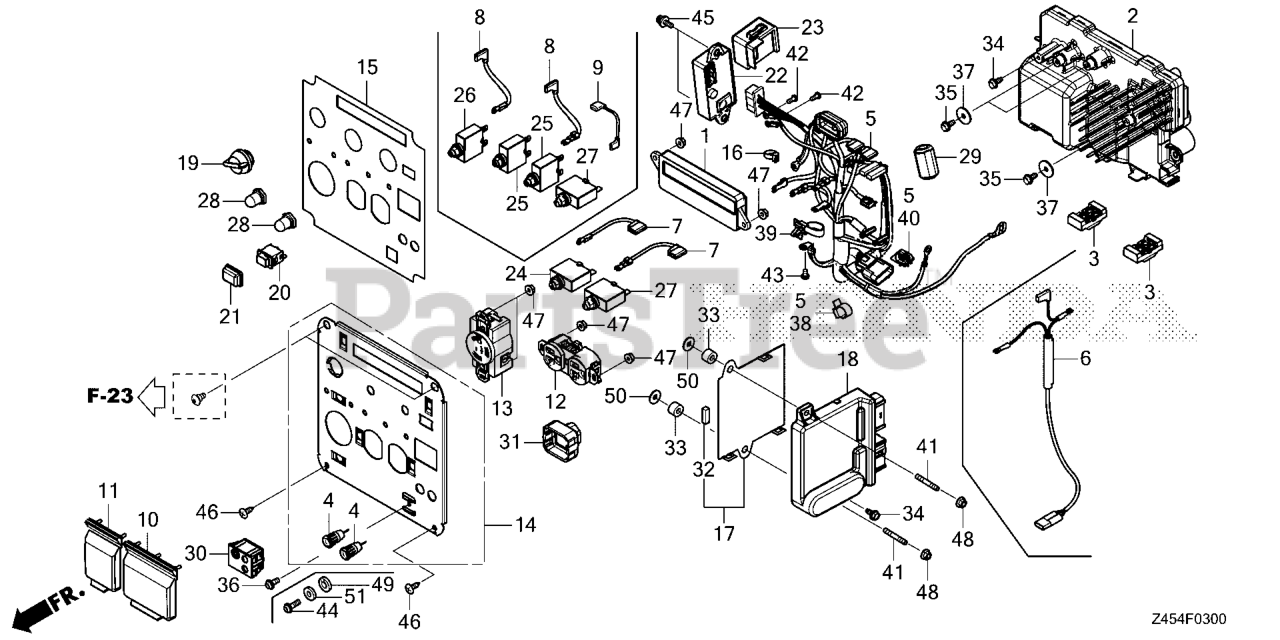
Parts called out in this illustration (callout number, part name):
1	KIT, INDICATOR UNIT
2	UNIT COMP INVERTER
3	RUBBER, INVERTER
4	SOCKET, COMPOSITE
5	HARN, CONTL WIRE
7	WIRE, TERMINAL
10	COVER COMP (20A)
11	COVER COMP (30A)
12	RECEPTACLE ASSY. (125V-20A) (MATSUSHITA)
12	RECEPTACLE (20A/125V) (CONFIRM RECEPTACLE AS NON-GCFI. IF GCFI, TRY #42.)
13	RECEPTACLE (30A/125V)
13	RECEPTACLE (30A-125V)
14	PANEL COMP, CONTL
15	MARK, CONTROL PANEL
16	TIE, CABLE (C)
17	COVER COMP, ECU
19	SW ASSY., ENG STOP
20	SW COMP, IDLE CONTL
24	PROTECTOR, CIRCUIT (20A) (BLACK)(JOEMEX)
27	PROTECTOR, CIRCUIT (30A) (BLACK)
28	COVER, CIRCUIT PROTECTOR
29	FILTER, SUB NOISE
30	LED ASSY., INDICATER
32	SEAL A, L. PANEL
33	COLLAR, FR. PANEL
34	BOLT, FLANGE (5X10) Use from Engine SN 2327377.
35	BOLT, FLANGE (5X12)
36	SCREW, PAN (5X12)
37	WASHER, PLAIN (20MM)
38	BAND, WIRE HARNESS
39	BAND, WIRE HARNESS (150MM) (Honda Code 1352103). (BLUE)
40	CLIP, CONNECTOR (DARK BROWN)
41	BOLT 2, STUD (5X25)
42	SCREW, PAN (3X8)
43	SCREW, PAN (5X8)
45	SCREW-WASHER (5X14)
46	SCREW, TAPPING (5X16) (PO)
47	NUT, FLANGE (4MM)
48	NUT, FLANGE (5MM)
50	WASHER, PLAIN (5MM)
